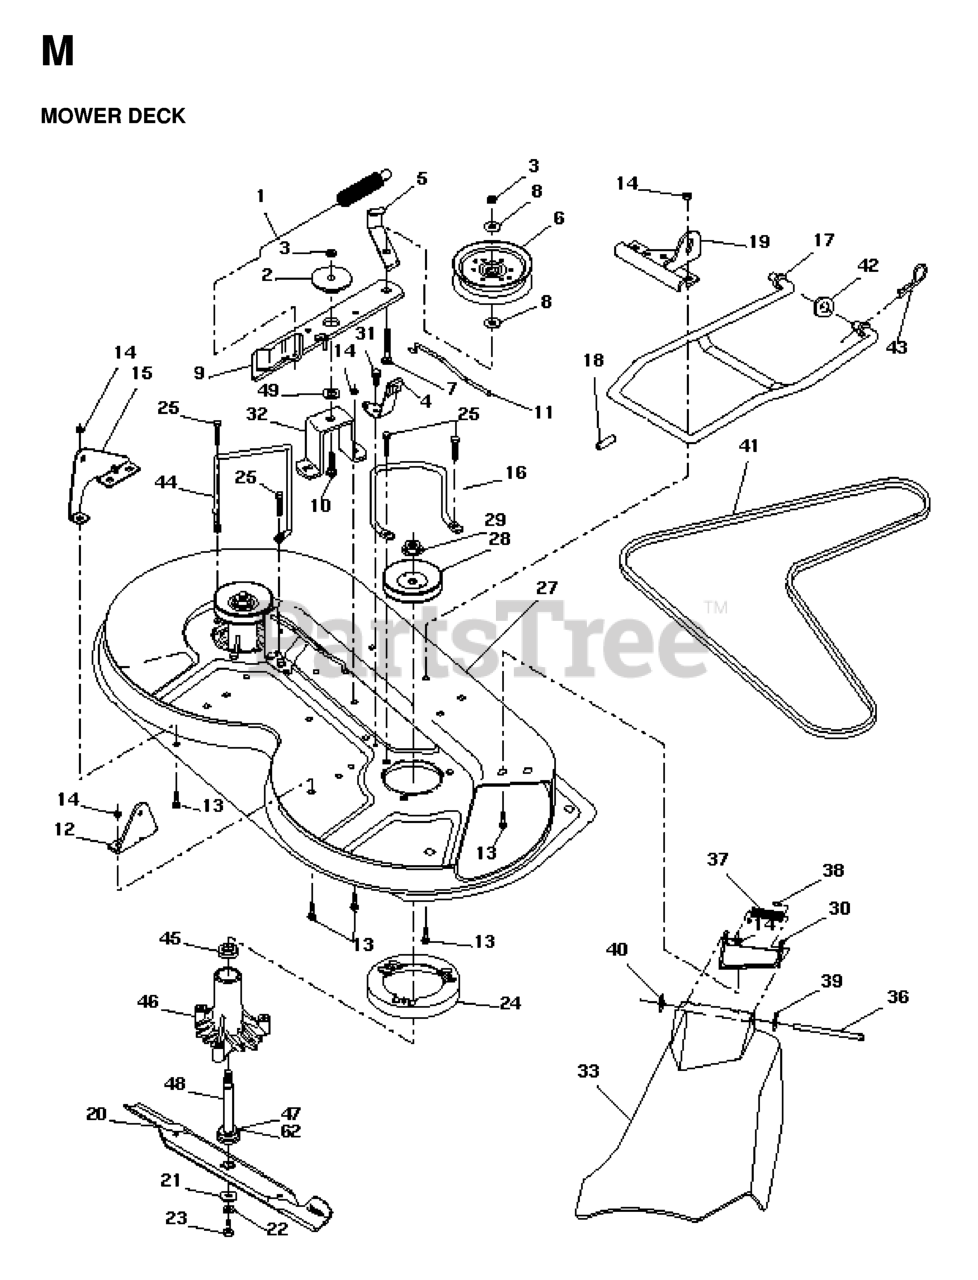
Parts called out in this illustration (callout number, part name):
1	SPRING-MOWER CLUTCH
2	SPACER RETAINER
4	BRAKE ASSEMBLY
5	IDLER BELT GUIDE
6	PULLEY.IDLER.FLAT.MOWER.BLK.PT
8	WASHER
9	IDLER ARM ASSY
10	BOLT.3/8-14X1.25
12	BRKT LIFT REAR
13	RP BOLT 5/16-18 X3/4 ZN/YEL GR
14	LOCKNUT
15	BRKT LIFT REAR LH
16	BELT KEEPER
17	MOWER LINK STABILIZER
18	PIN GROOVE
19	BRKT LINK STABILIIZER
20	BLADE, HI-LIFT 36" PREMIUM
21	WASHER.BLADE
22	LOCKWASHER
23	BLADE BOLT
24	STRIPPER
25	SCREW THDROL ROLLING WASHER HD
27	MOWER HOUSING
28	PULLEY, MANDREL
29	NUT
30	BRACKET ASM DEFLECTOR
31	Screw 5/16-18 x 1/2 Hex, Self Tapping 5/16-18 x 1/2
32	SUPT,IDLER ARM
33	DEFLECTOR
36	HINGE ROD
37	SPRING TORSION
38	CAP-SLEEVE LT
39	Washer 11/32 x 5/8 x 16 Ga SD
40	NUT PUSH M
41	BELT
42	WASHER
43	SPRING RETAINER
46	HOUSING.MANDREL.VENTED (MACHD)
47	BEARING.BALL.#6204.(MANDREL)
48	SHAFT ASM VENT
49	HARDENED WASHER
62	WASHER FELT
